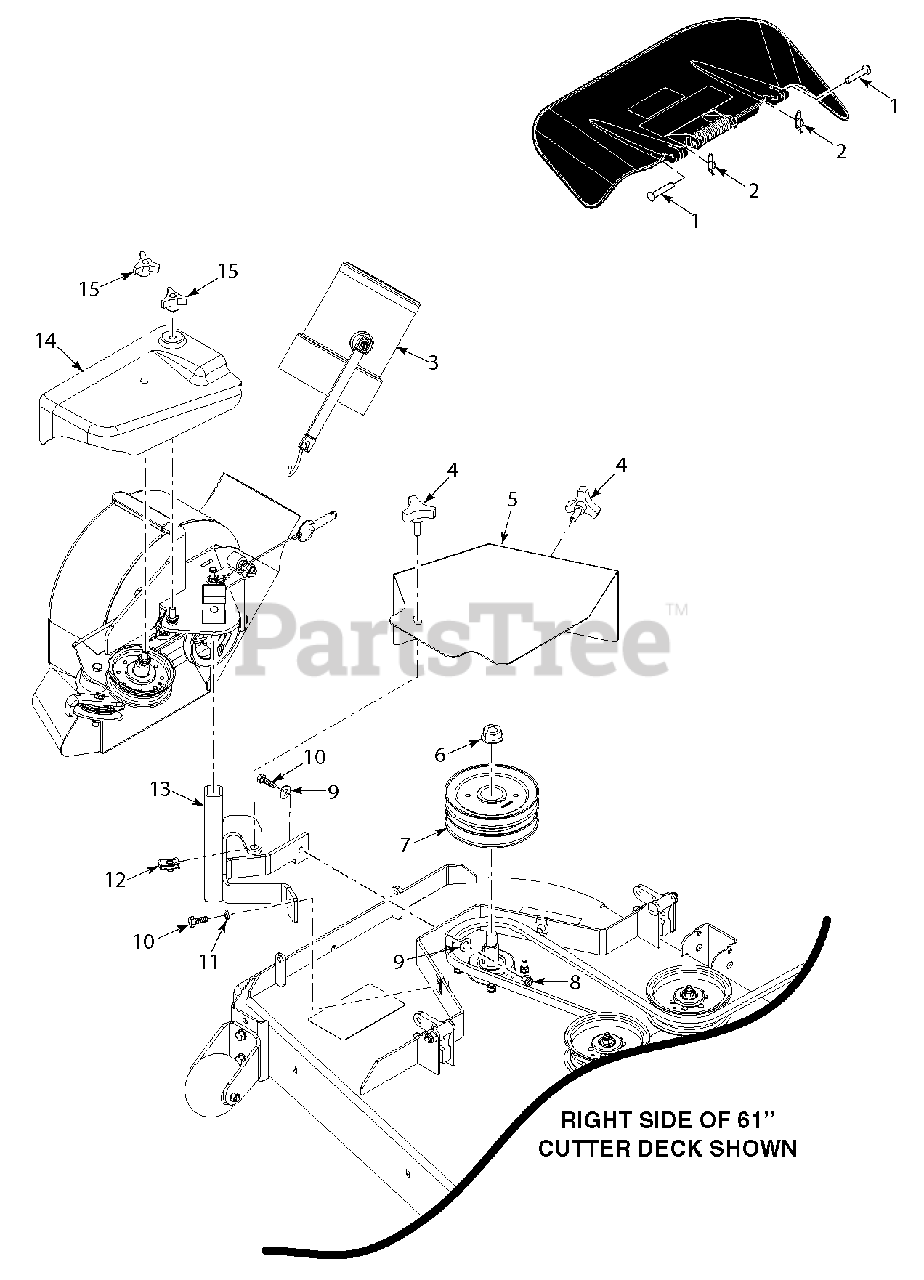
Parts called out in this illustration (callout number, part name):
1	Clevis Pin, 5/16 x 1-1/2"
2	Pin, Rue Cotter 5/16"
3	Adapter w/Strap
4	Knob w/Stud
5	Belt Cover - 52
5	Belt Cover - 61
6	Nut, 3/4-16 Spriral Lock
7	Pulley, Double Groove - 52
7	Pulley, Double Groove - 61
8	Nut, Elastic Stop 3/8-16
9	Flatwasher, 3/8-.391 x .938 x .105
10	Bolt, Hex Head 3/8-16 x 1-1/4"
11	Lockwasher, 3/8" Spring
12	U-Nut, 3/8-16
13	Mounting Post Assembly, Blower - 52
13	Mounting Post Assembly, Blower - 61
14	Belt Cover - 52
14	Belt Cover - 61
15	Wing Nut
